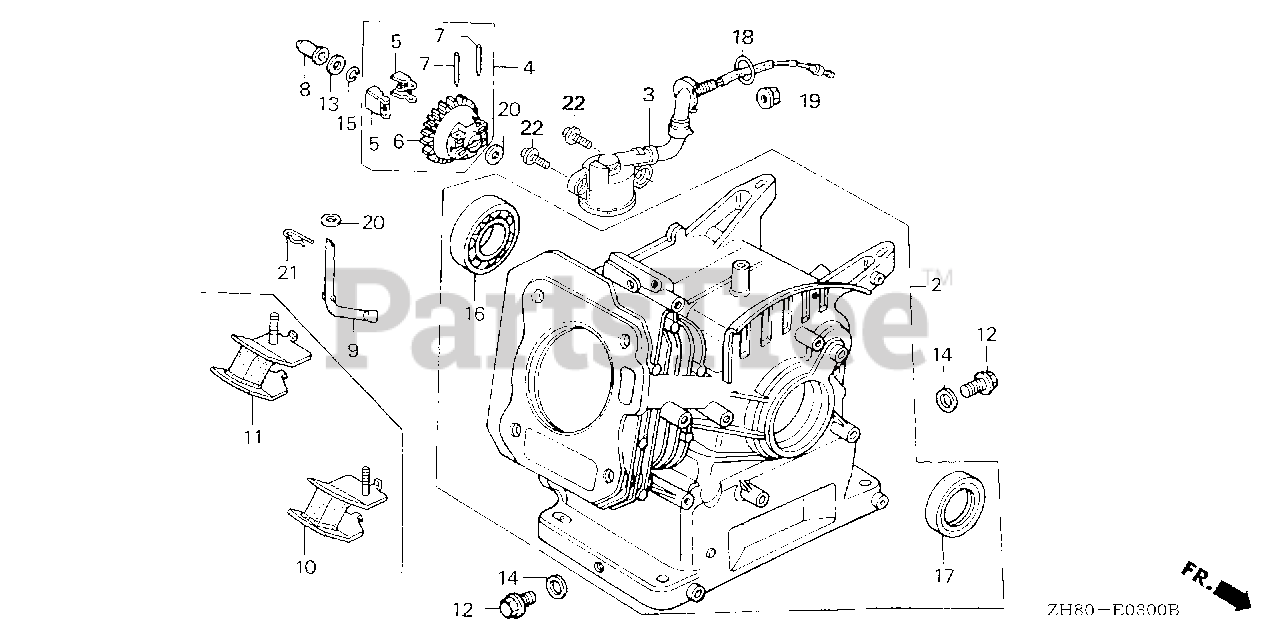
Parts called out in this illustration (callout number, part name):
2	CYLINDER ASSY. (OIL ALERT)
3	SWITCH ASSY., OIL LEVEL
4	GOVERNOR ASSY.
5	WEIGHT, GOVERNOR
6	HOLDER, GOVERNOR WEIGHT
7	PIN, GOVERNOR WEIGHT
8	SLIDER, GOVERNOR
9	SHAFT, GOVERNOR ARM
12	BOLT, DRAIN PLUG
13	WASHER, THRUST (6MM)
14	WASHER, DRAIN PLUG (10.2MM)
15	CLIP, GOVERNOR HOLDER
16	BEARING, RADIAL BALL (6205TMB) (NTN)
17	OIL SEAL (25X41X6)
18	O-RING (14MM) (ARAI)
18	O-RING (14MM) (NOK)
19	NUT, FLANGE (10MM)
20	WASHER, PLAIN (6MM)
21	PIN, LOCK (8MM)
22	BOLT, FLANGE (6X12)
